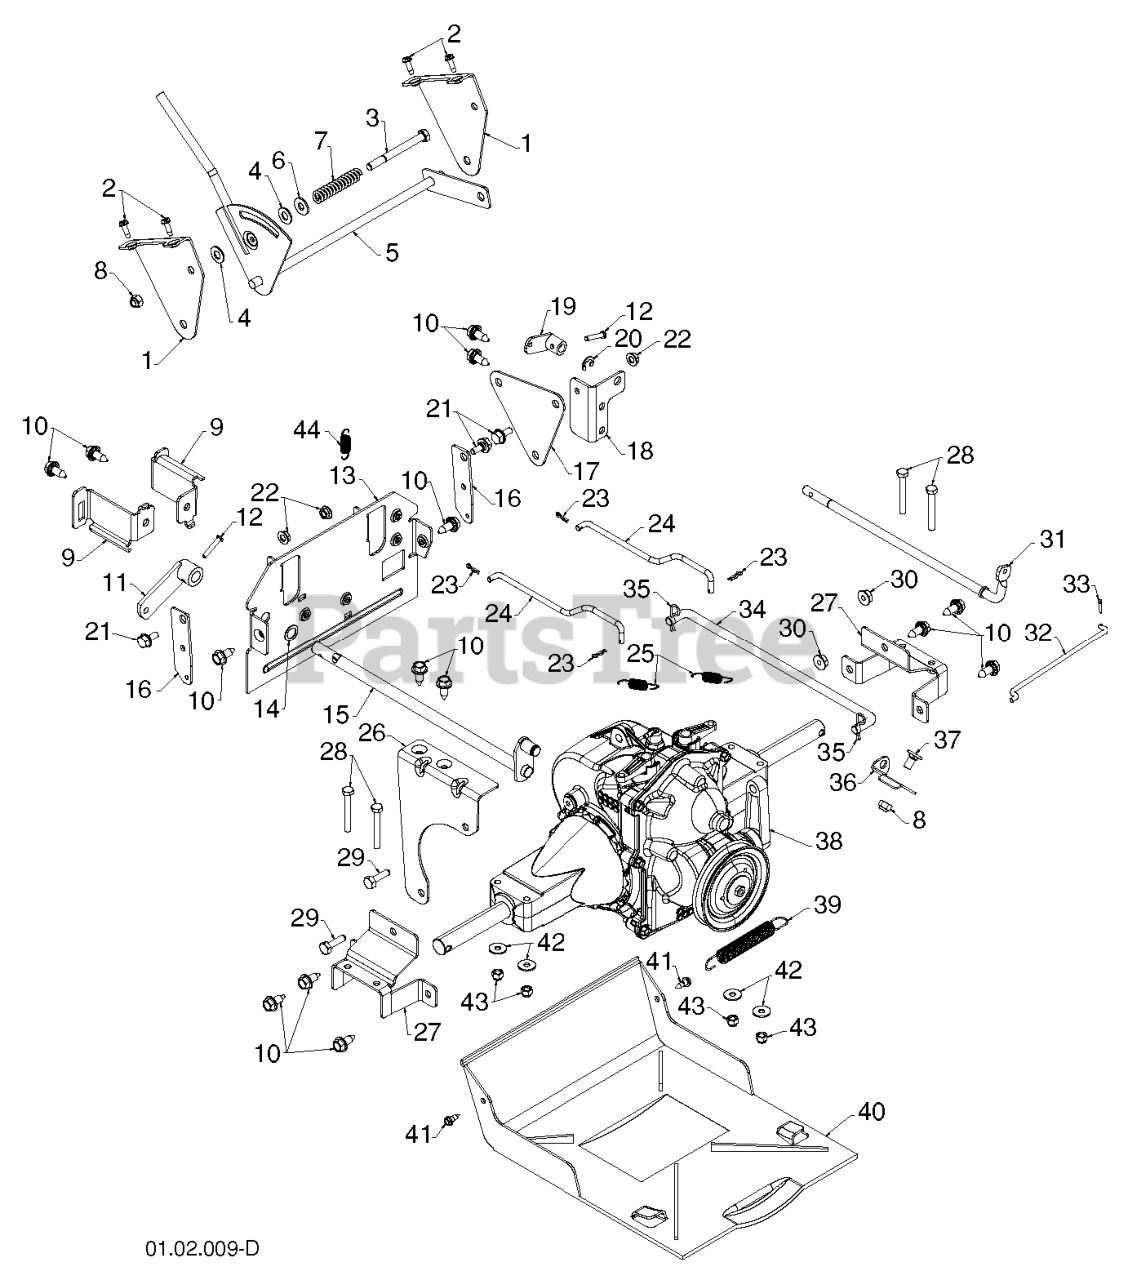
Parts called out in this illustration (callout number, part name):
1	BRACKET.SHIFT.HYDRO
2	SCREW #10-24 X 5/8
4	WASHER, NYLON FRICTION
5	CONTROL.WLD.HYD.II
6	WASHER.20X8.5
7	SRPING.FRICTION.HYDRO
8	NUT.71038.31-18.HEX.NYLOCK
9	BRACKET.CABLE.PNT.HYDRO
10	BOLT.HEX.HD.WASHER.5/16-18X.75
11	ARM, AUGER CONTROL
12	CLEVIS PIN
13	PLATE.REAR.HYDRO.PNT.ORANGE
14	THRUST WASHER
15	CONTROL.SHAFT.ASM
16	LEVER.STEER.CABLE.PNT.SNOW
17	BRACKET.SPEED.PIVOT.YZP
18	BRACKET.SPEED.PIVOT.YZP
19	ARM.HYD.CLUTCH
20	E-RING.RETAINER.REINFORCED.375
21	BOLT.SHOULDER.3/X.25
22	NUT.HEX.FLANGE.1/4
23	COTTER PIN (3 2)(2 2MC)
24	ROD.STEER.HYD
25	SPRING.RETURN
26	BRACKET.HYDRO.STABILIZER
27	BRACKET.TRANSMISSION.MOUNT
28	BOLT.HEX.1/4-20X2.00.HEX.HD.
29	BOLT RB
30	NUT.LOCK.5/16-18
31	SHAFT.HYD.CLUTCH
32	RP ROD.HYD.CLUTCH
33	RETAINER CLIP
34	ROD.SPEED.CONT.HYD.SNOW
35	SPRING RETAINER
36	BRACKET.HYD.CLUTCH.
37	BOLT.CARRIAGE.5/16-18X
38	TRANSAXLE HYDRO.II PS 71876
39	SPRING, BRAKE
40	PAN.BOTTOM.PLASTIC.SNOW
41	SCREW, HEX HEAD, TAPPING
42	WASHER
43	LOCKNUT.NYLOC.1/4-20
